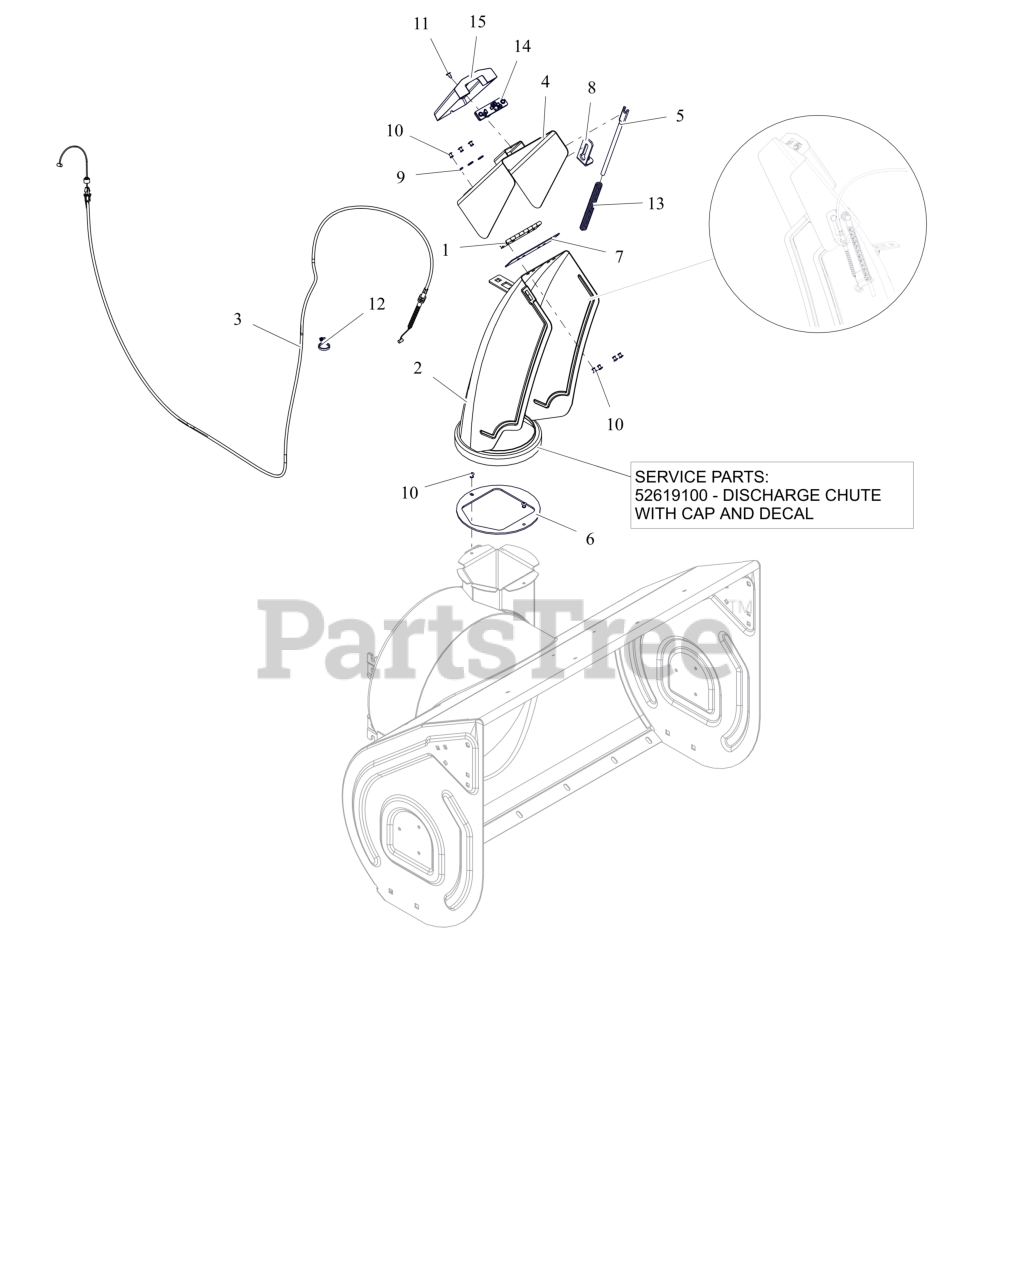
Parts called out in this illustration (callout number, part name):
2	CHUTE,DISCHARGE,RMT,ID
2	CHUTE, DISCHARGE W/CAP LIGHT
3	CABLE, E-CHUTE CAP
4	CAP, REMOTE - LARGE
5	ROD, DEFLECTOR CAP
6	BAFFLE, DISCHARGE NECK
7	CAP SEAL 5.50
8	BRACKET, ANCHOR-CHUTE CABLE
9	WSHR,FLT .196X.500X.066 ZCC
10	RVT, POP .1875 ZCC
11	SCR, TAP #10-24X.375 ZCC P80
12	CABLE TIE W/ TREE (.25 HOLE)
13	SG-COMP .08X.40X6.50 14#/IN
14	LIGHT- LED - 3BAR HEADLIGHT
15	COVER, LIGHT - LED W/DECAL
